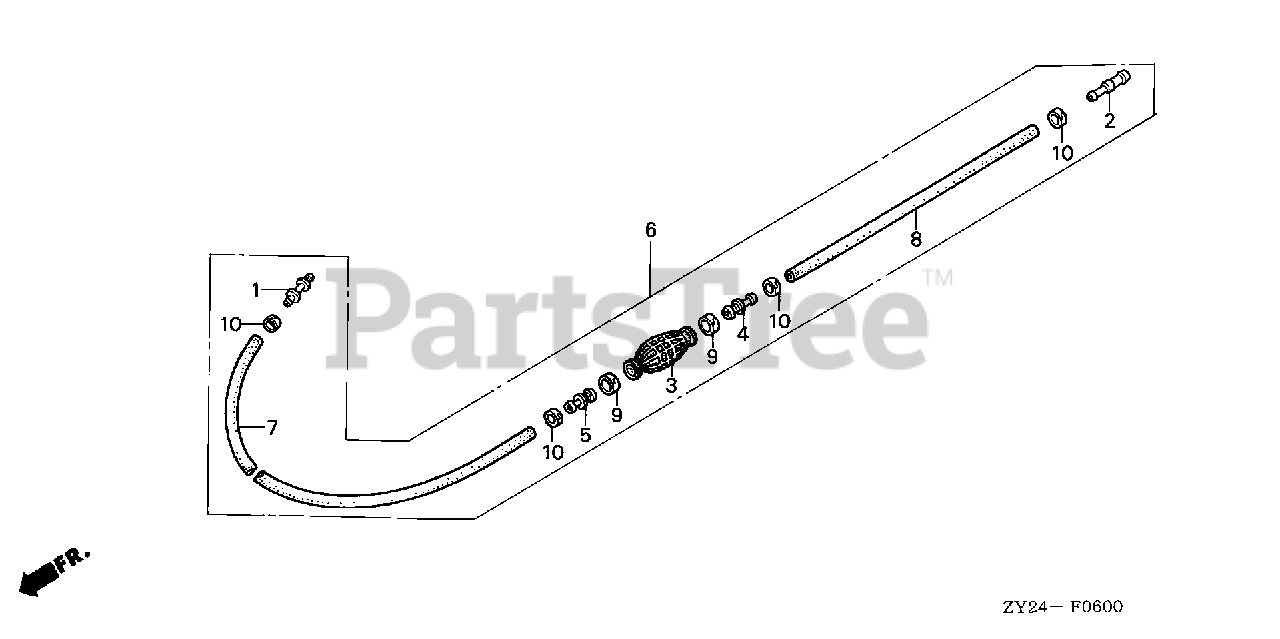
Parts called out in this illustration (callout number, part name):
1	JOINT, FUEL TUBE
2	JOINT, FUEL TUBE
3	BULB, PRIMER
4	VALVE, IN.
5	VALVE, OUTLET
6	TUBE ASSY., FUEL (JOINT TYPE)
7	TUBE, FUEL LONG (7.3X2000)
8	TUBE, FUEL SHORT (6.3X500)
9	BAND, TUBE CLIP (20MM)
10	BAND, TUBE CLIP (12.5MM)
